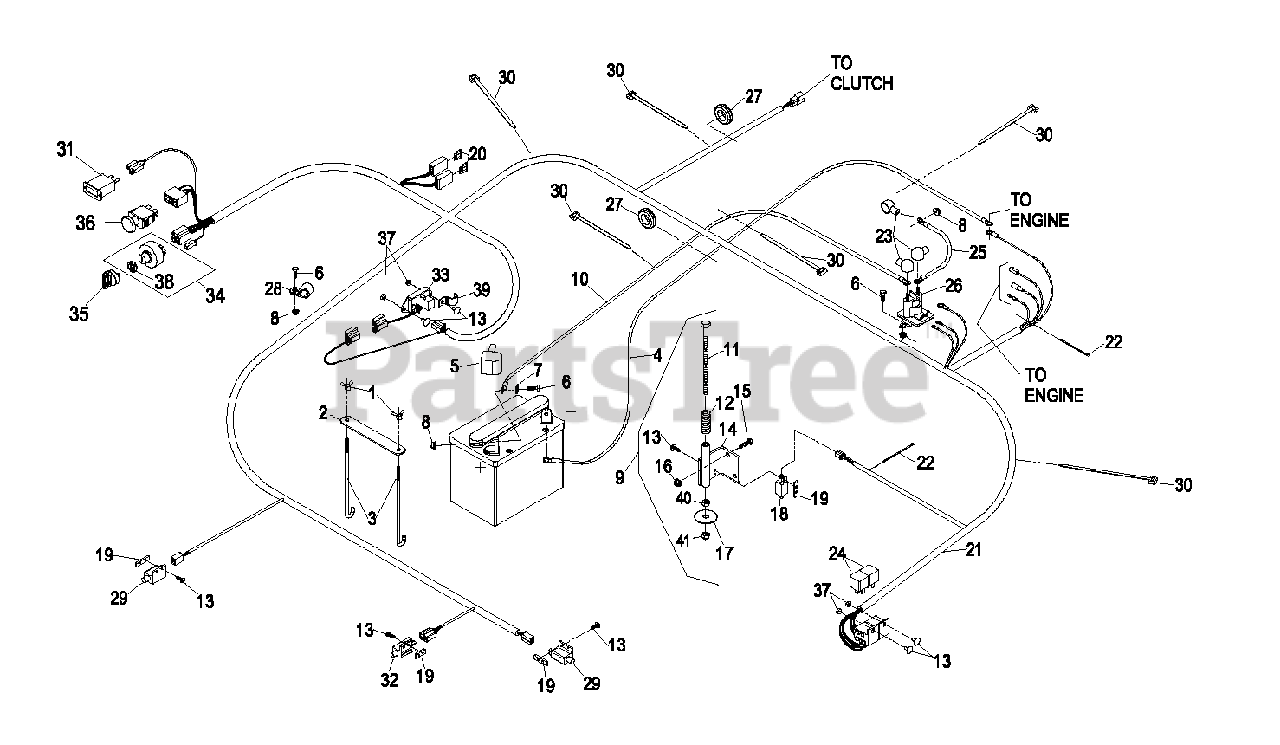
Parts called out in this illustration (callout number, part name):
1	WINGNUT
2	STRAP-HOLDDOWN, BATTERY
3	BOLT-HOLDDOWN
4	CABLE-GROUND, NEGATIVE
6	SCREW-HH
7	WASHER-FLAT
9	ASM,SEAT SWITCH ACTUATOR
11	SCREW-HH
12	SPRING-SWITCH, SEAT
13	SCREW-PPH
14	BRACKET-SWITCH, SEAT
15	SCREW-HH
18	SWITCH-CLOSED, NORMALLY
19	PLATE-TAPPED
20	FUSE-BLADE TYPE, 20 AMP
21	HARNESS,WIRE LCT BV
22	TIE-CABLE
23	INSULATOR-SOLENOID
27	GROMMET
28	CLIP-LOOM
29	SWITCH-OPEN, NORMALLY
30	TIE-PLASTIC
31	METER-HOUR
33	MODULE-DELAY, SEAT
34	ASM,SWITCH W/NUT
35	KEY-IGNITION
35	KEYS-IGNITION (SPARE PAIR
36	SWITCH-PTO
37	NUT-LOCK, NI
38	NUT-SWITCH, IGNITION
39	CLIP-HALF, LOOM
40	NUT-HEX
41	NUT-LOCK, NI
